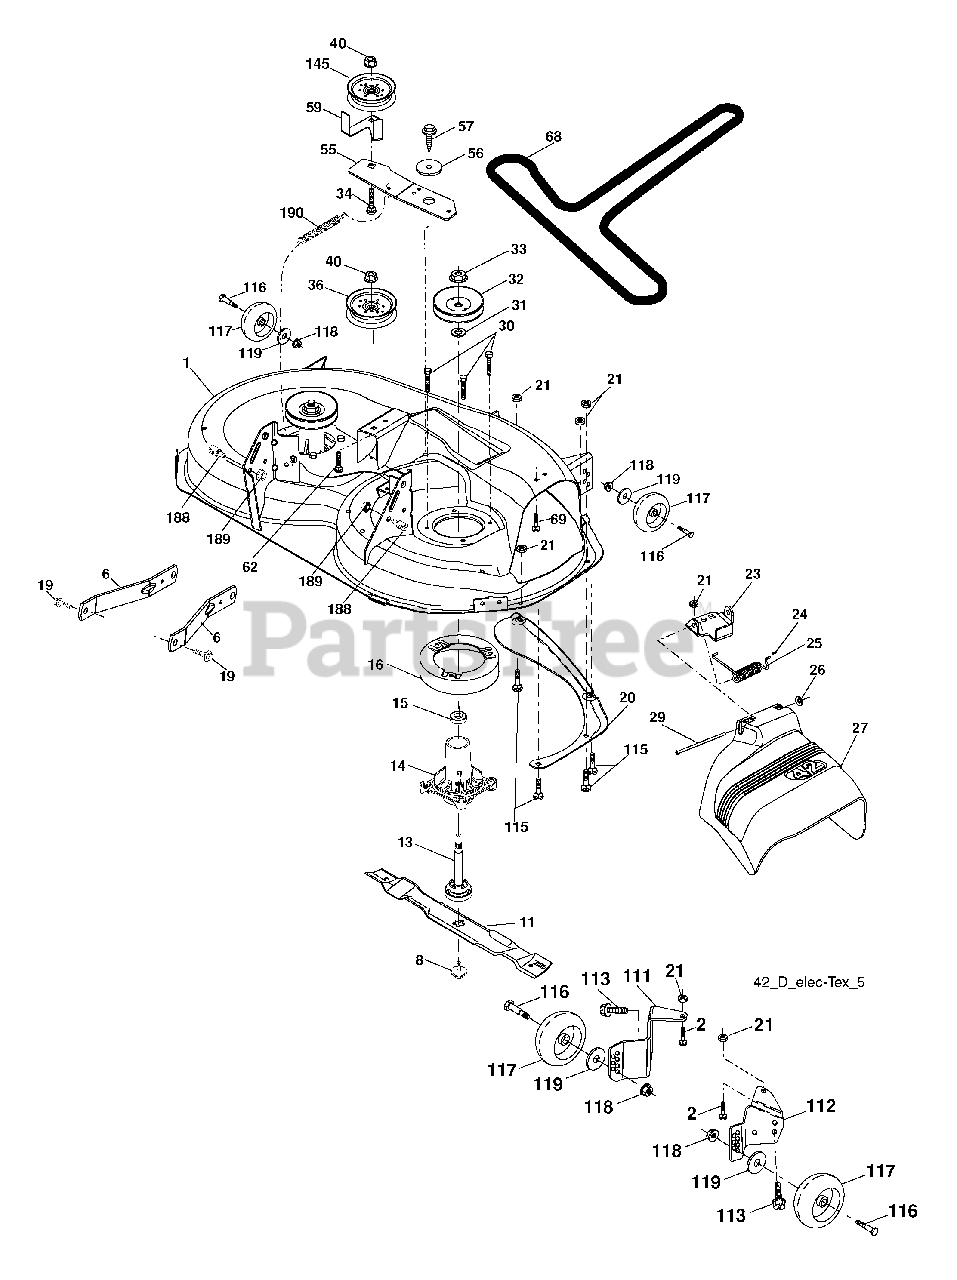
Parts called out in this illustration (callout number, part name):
1	Mower Deck Assembly, 42"
2	Bolt Rdhd Sqnk 5/16-18 unc x 3/4
6	Arm Susp. Rear
8	Bolt/Washer Asm 7/16-20 unf
11	Blade Mower 42" Hi-Lift
11	Blade, Mulching 42" Std
11	Blade Mulching 42" Premium
13	Shaft Assembly, Mandrel
14	Housing, Mandrel
15	Bearing, Ball, Mandrel
16	Stripper, Mandrel Deck
19	Bolt, Shoulder
20	Baffle, Vortex
21	Nut
23	Bracket, Deflector Mower 42
24	Cap, Sleeve 80 x 112 Blk Mower
25	Spring, Torsion, Deflector
26	Nut, Push Phos & Oil
27	Shield, Deflector 42" Blk
28	Washer 11/32 x 5/8 x 16 Ga.
29	Rod, Hinge 42" 6 75 W/G
30	Screw Thdrol
31	Washer, Spacer Mower Vented
32	Pulley, Mandrel
33	Nut, Toplock
34	Bolt Carr SH 3/8-16 x 1-1/2 Gr.5
36	Pulley, Idler, Flat
40	Nut Lock 3/8-16
45	Pulley Idler Glat
55	Arm, Idler
56	Spacer, Retainer
57	Screw 3/8-16 x 1
59	Guard TUV Idler
61	Spring Ext Elect. Clutch
62	Bolt Rdhd Sqnk 3/8-16 unc x 2
68	V-Belt, 42" Mower
69	Bolt, Carriage 5/16-18 x 5/8
111	Bracket Wh Gauge RH
112	Bracket Wh Gauge LH
113	Screw 5/16-18
115	Nut Crownlock
116	Bolt, Shoulder
117	Wheel, Gauge
118	Nut Centerlock 3/8-16
119	Washer 13/32 x 1-1/4 x 12 Ga.
145	Pulley Idler Flat
188	Stud Fastner W/D Anti-Rotation
189	Nut Lock Hex Flange 5/16-18
190	Spring Mower Drive
